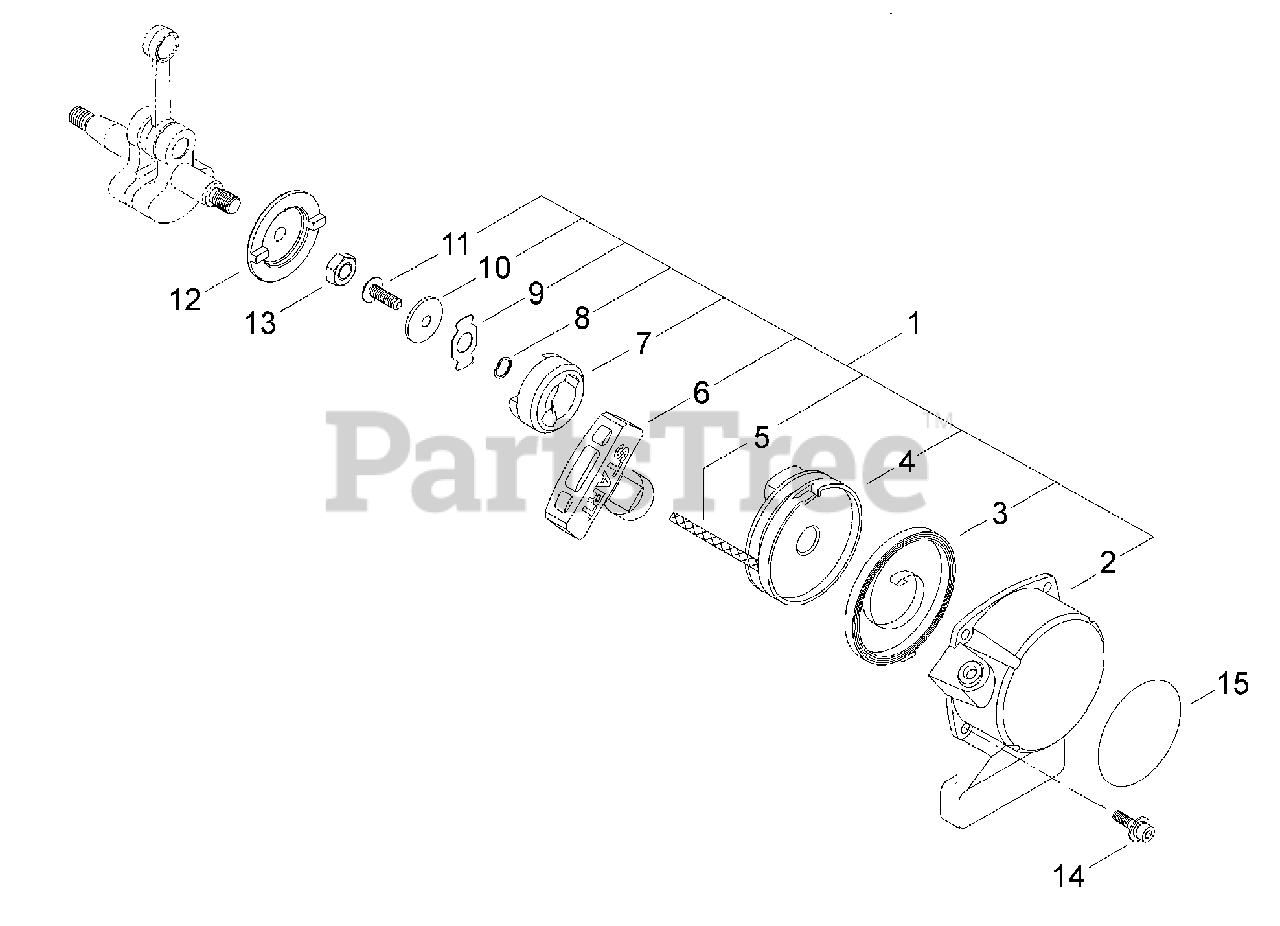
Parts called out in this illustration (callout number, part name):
1	STARTER ASSY
2	CASE, STARTER
3	SPRING, REWIND
4	REEL, ROPE
5	ROPE, STARTER
6	GRIP, STARTER
7	PAWL, STARTER
8	WASHER - SPRING
9	RETAINER
10	WASHER - 5
11	SCREW - 5
12	PAWL
13	NUT - 8
14	SCREW - 4X16
15	LABEL - C4
